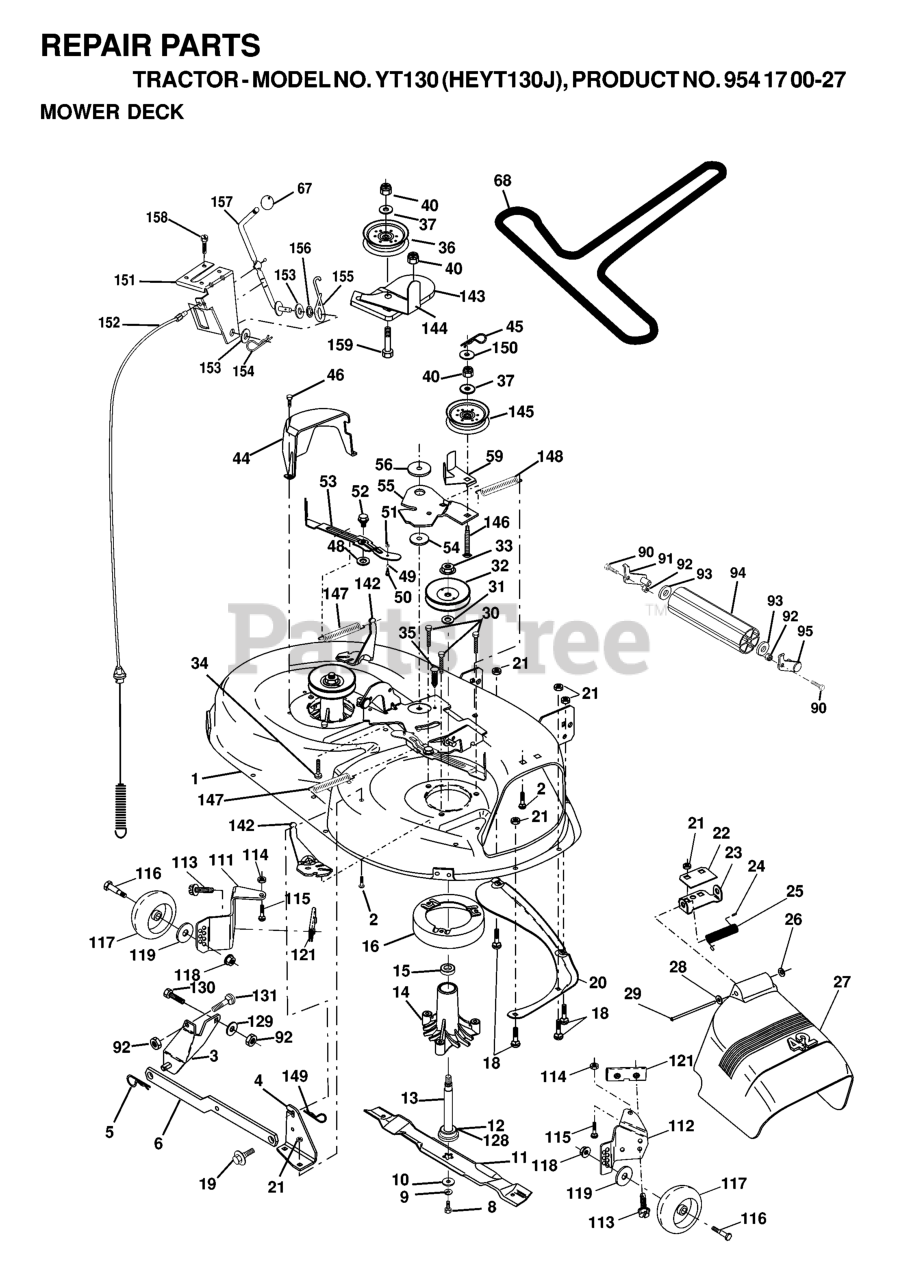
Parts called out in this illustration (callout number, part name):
1	42" DECK KIT
2	RP BOLT 5/16-18 X3/4 ZN/YEL GR
3	BRKT ASM SWAY BAR
4	BRACKET SWAY BAR 42" DECK
5	RETAINER-SPRNG RB
6	REAR SUSP ARM
8	BLADE BOLT
9	LOCKWASHER
10	WASHER.BLADE
11	BLADE 42", YTH 160
12	BEARING.BALL.#6204.(MANDREL)
13	SHAFT ASM VENT
14	HOUSING.MANDREL.VENTED (MACHD)
16	STRIPPER
18	BOLT
19	BOLT SHD 5/16-18
20	BAFFLE.VORTEX
21	LOCKNUT
22	STIFFENER BRACKET
23	DEFLECTOR BRACKET
24	CAP-SLEEVE LT
25	SPRING TORSION
26	NUT PUSH M
27	SHIELD DEFLECTOR
28	Washer 11/32 x 5/8 x 16 Ga SD
29	ROD.HINGE
30	SCREW THDROL ROLLING WASHER HD
31	WASHER
32	PULLEY/MANDREL
33	NUT
35	FASTENER.XMAS.TREE
36	FLAT IDLER PULLEY
37	WASHER
44	GUARD MANDREL LH BLACK
45	RETAINER M
46	SCREW.1/4-20X5/8
49	ROLLER ASSY
52	BOLT.SHOULDER.5/16-18
53	ARM
54	HARDENED WASHER
55	ARM IDLER 42" MOWER LT/YT
56	SPACER.RETAINER.MOWER
59	GUARD, BELT
67	KNOB T (3/8 HOLE)
68	BELT
90	BOLT
91	BRACKET LH (A)
92	NUT
93	Washer 1 17/32 X 7/8 X 16 Ga
94	NOSE ROLLER
95	BRACKET RH (B)
111	BRACKET WHEEL GAUGE LH 42" DK
112	BRACKET WHEEL GAUGE RH 42" DK
113	SCREW 5/16"
114	NUT
115	BOLT.CARR.5/16-18X1/2
116	BOLT M
117	WHEEL.GAUGE.STANDARD
118	LOCKNUT
119	WASHER.5/16.FLAT.STE.STD.
121	BRACKET.EXTRUDED.GAGE.WHEEL
128	WASHER FELT
129	WASHER
131	BOLT D
142	ARM SPRING BRAKE MOWER
143	BRACKET, ARM IDLER
144	DNO KEEPER.BELT.42".CLUTCH.CBL
145	PULLEY
146	BOLT, CARRIAGE IDLER
147	SPRING EXTENSION
148	IDLER RETURN SPRING
149	KIT CYLINDER #70331
151	BRACKET.CLUTCH.CABLE
152	CLUTCH CABLE 42"
153	WASHER FLAT 3/8"
154	SPRING RETAINER
155	SPRING RETENTION LEVER
156	SPACER.CLUTCH.CABLE
157	ROD CLUTCH CABLE 3/8"
158	SCREW LT
